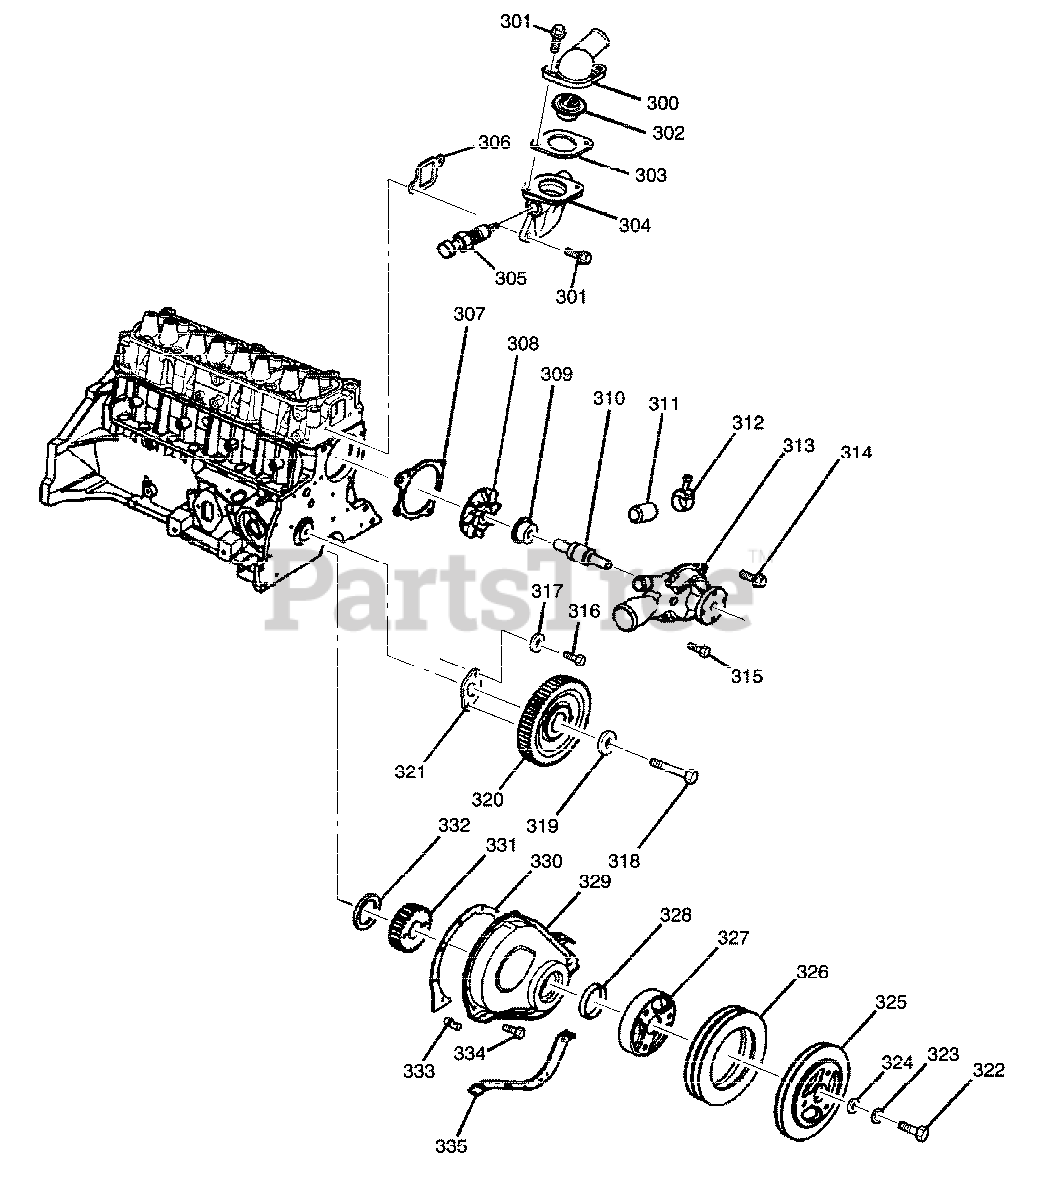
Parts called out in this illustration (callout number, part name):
301	* BOLT
308	* IMPELLER
309	* SEAL
310	* BEARING
313	WATER PUMP KIT
314	* BOLT
315	* BOLT
316	* BOLT
317	* WASHER
318	* BOLT
319	* WASHER
320	* GEAR
321	* PLATE
322	* BOLT
323	* WASHER
324	* ABSORBER
325	* BALANCER
326	* PULLEY
327	* HUB
328	* ABSORBER
329	* COVER
330	* GASKET
331	* GEAR
332	* SEAL
333	* NOZZLE
334	* BOLT
335	* REINFORCEMENT
